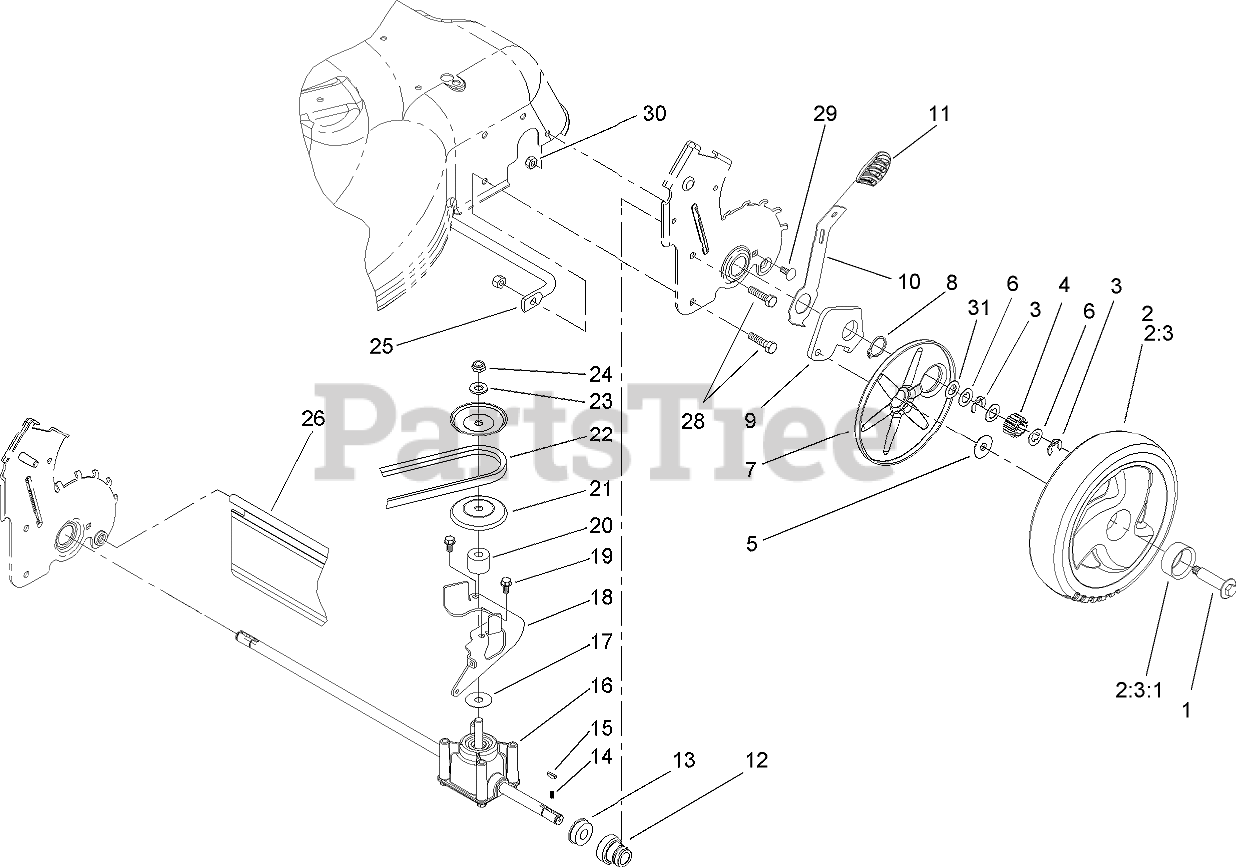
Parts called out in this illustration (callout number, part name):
1	BOLT-SHOULDER
2	Wheel Gear ASM
2:3	WHEEL ASM
2:3:1	BUSHING
3	RING-CLIP, LOCKING
4	Gear-Pinion, 15t
5	WASHER-STEPPED
6	Washer-Thrust
7	COVER
8	RING-RETAINING
9	Arm-Pivot, Rear (LH)
10	Arm-Spring
11	Knob-Lever, HOC
12	RETAINER-BEARING, HOC
13	BEARING-BALL
14	SPRING-COMPRESSION
16	TRANSMISSION ASM
17	WASHER-PLAIN
18	BRACKET-PIVOT, RWD
19	SCREW-HWH
20	SPACER
21	PULLEY-HALF
22	BELT-V
23	WASHER-FLAT
24	NUT-HEX
25	BRACE-PLATE, HOC
26	Shield-Trailing
28	SCREW-HH
29	SCREW-CARR
30	NUT-LOCK, NI
31	WASHER-PLAIN
